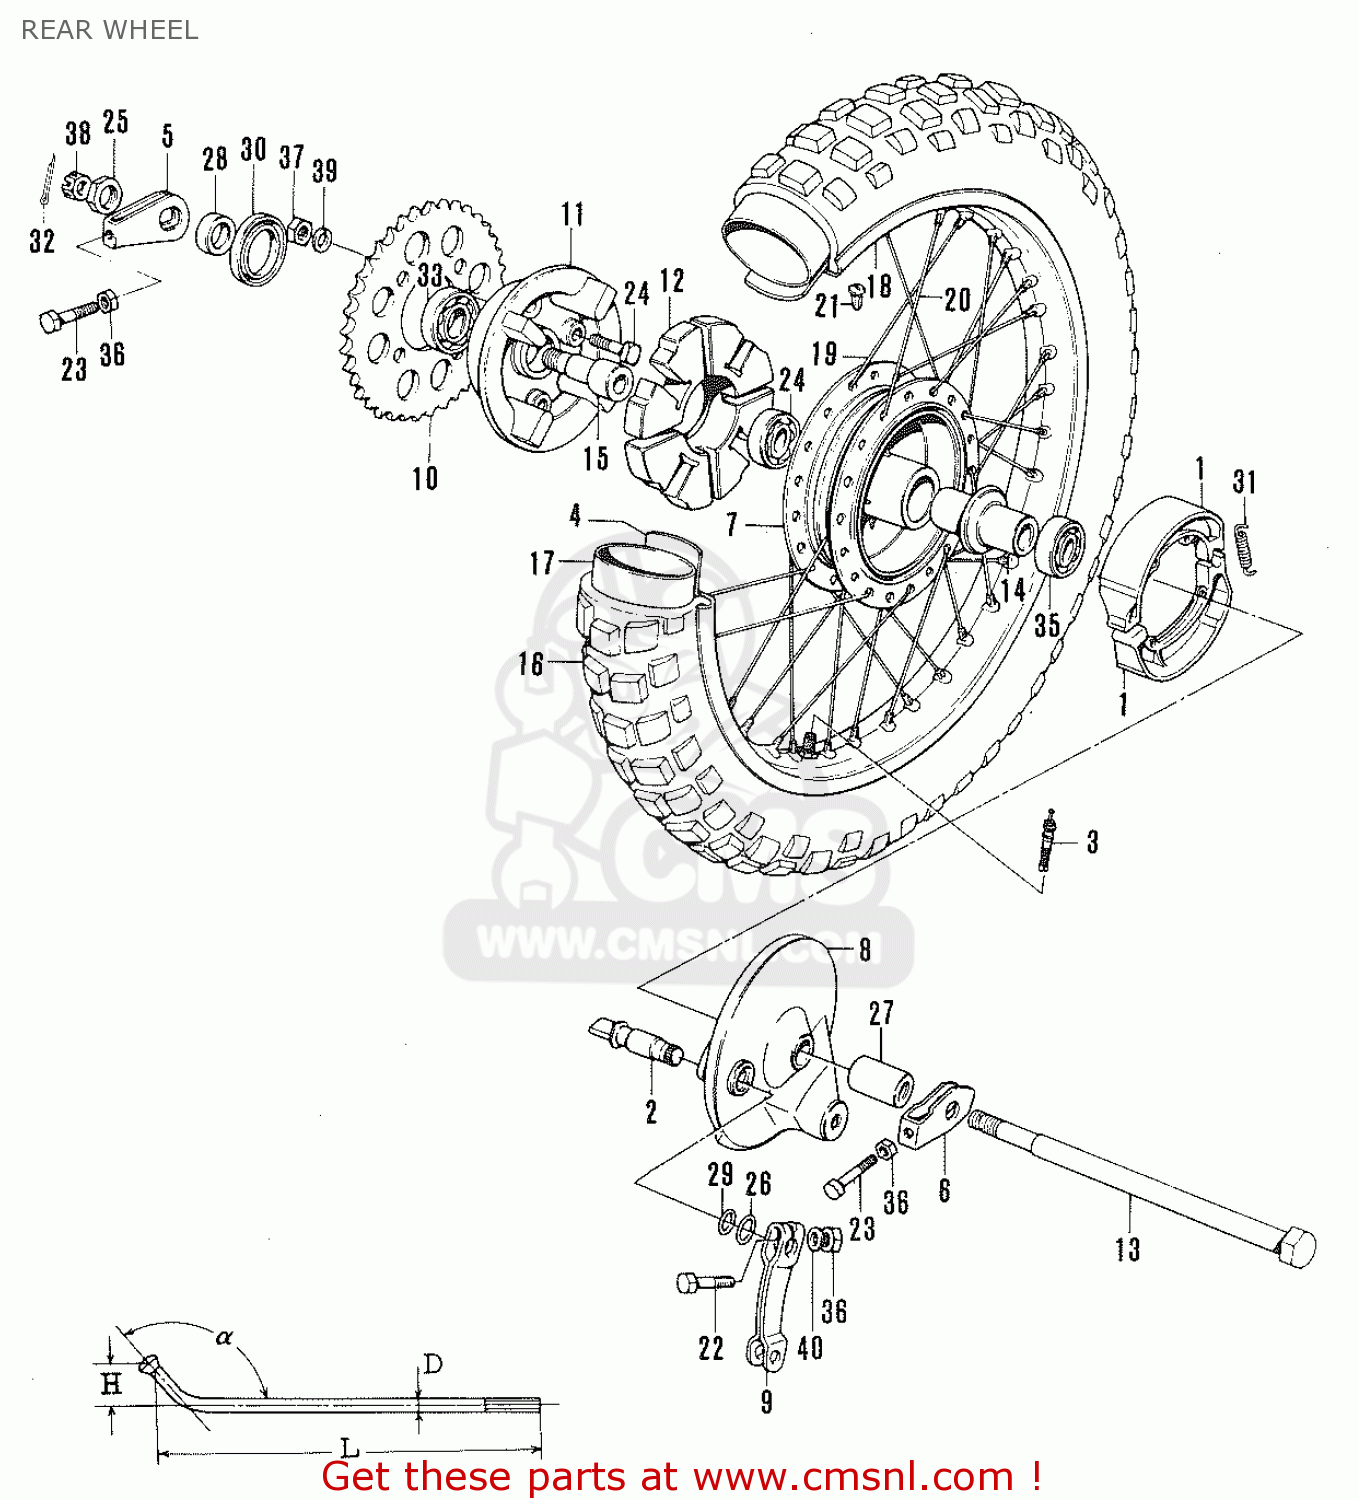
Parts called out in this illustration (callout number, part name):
1	SHOE,BRAKE
2	CAM,FRONT BRAKE
3	VALVE,INNER TUBE
4	PROTECTOR,INNER TUBE
5	ADJUSTER,CHAIN
6	ADJUSTER,CHAIN
7	HUB,REAR WHEEL
8	PANEL,REAR HUB
9	LEVER,REAR BRAKE CAM
10	SPROCKET,REAR
11	DRUM,RR SPROCKET
12	CUSHION,REAR DRUM
13	AXLE,REAR
14	SPACER,REAR HUB BEARING
15	SHAFT,RR SPROCKET DRUM
16	TIRE
17	SPOKE SET,REAR
18	RIM,REAR WHEEL
19	SPOKE SET,REAR WHEEL
20	SPOKE,RR WHEEL OUTER
21	NIPPLE,SPOKE
22	BOLT
23	BOLT(6X38)
24	BOLT(8X33.5)
25	NUT
26	WASHER(12.5X20X1)
27	SPACER(15.2X26X33)
28	SPACER(20X28X13)
29	O RING(D:2.5,ID:11.4)
30	OIL SEAL
31	SPRING(L:34)
32	PIN
33	Bearing
34	BEARING
35	BEARING
36	NUT
37	NUT
38	CASTLE NUT
39	LOCK WASHER
40	WASHER
